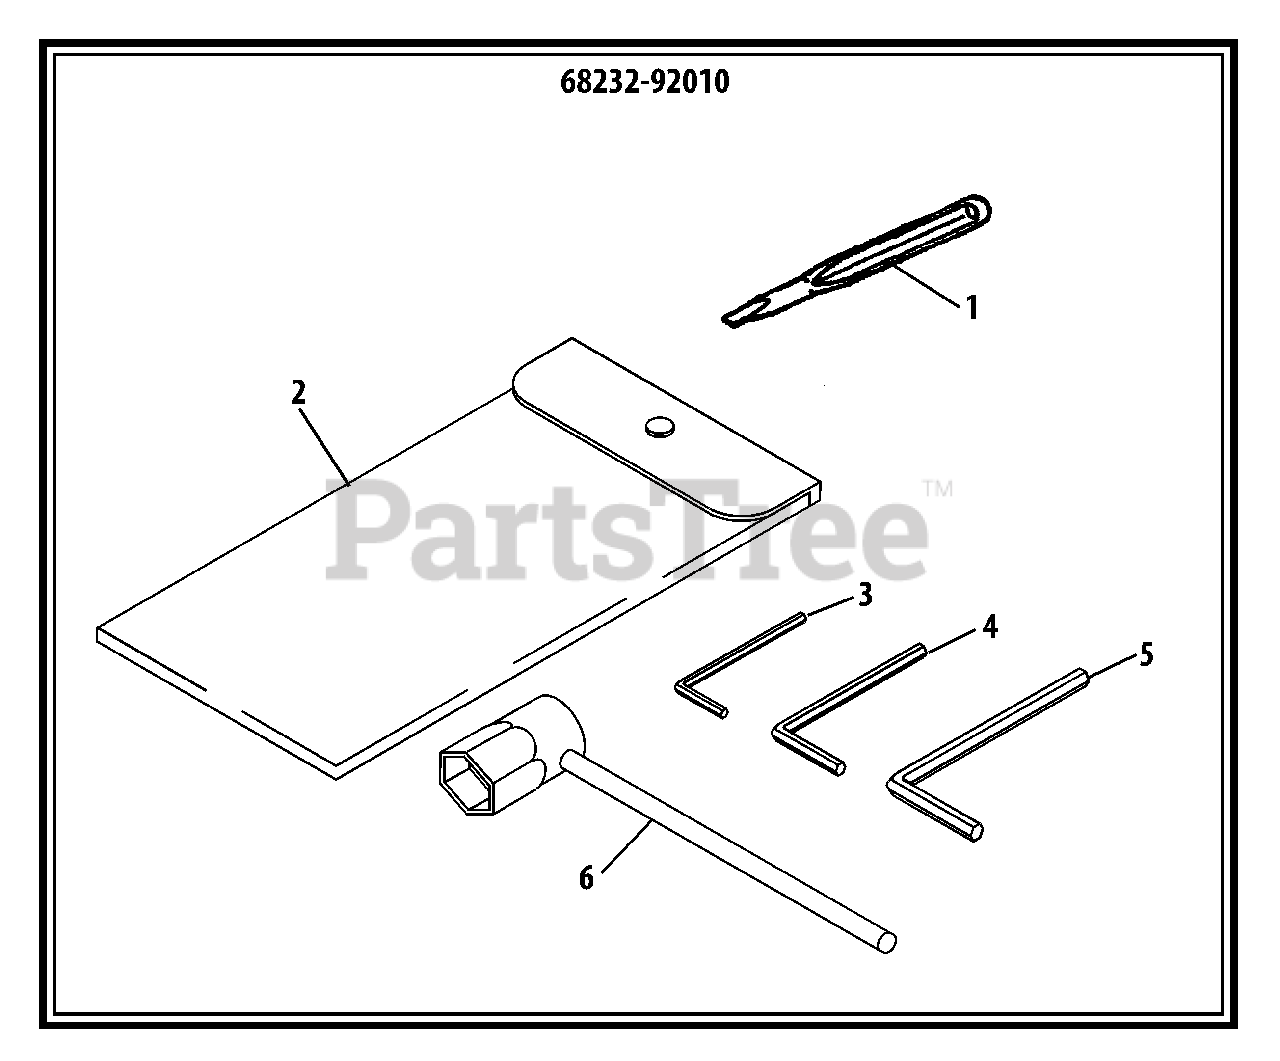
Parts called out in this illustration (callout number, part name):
1	SCREWDRIVER - PLASTIC
2	BAG, TOOL
3	HEX KEY - 3mm
4	HEX KEY - 4mm
5	HEX KEY - 6mm
6	SOCKET WRENCH
68232-92010	TOOL KIT
